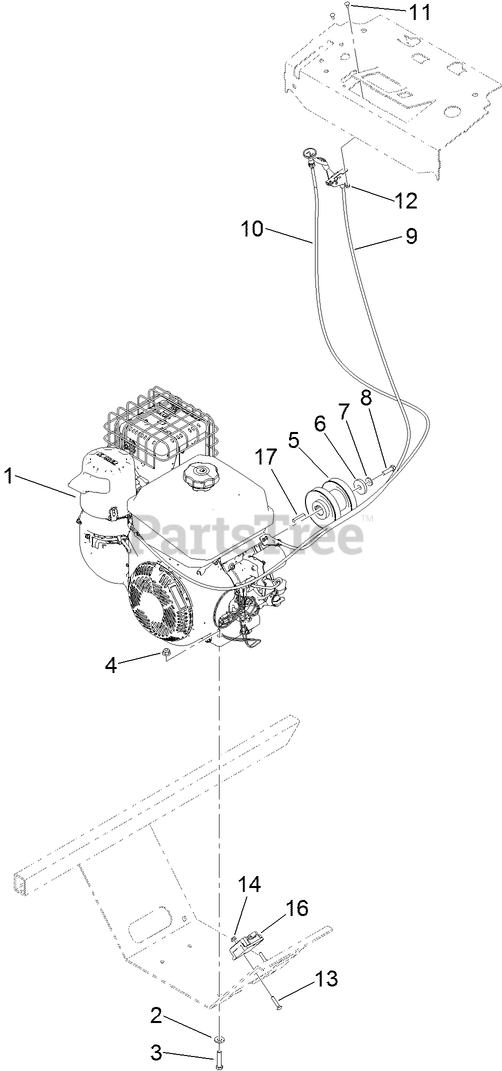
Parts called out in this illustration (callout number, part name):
2	WASHER-BELLEVILLE
3	SCREW-HH
4	NUT-HF, NI
5	PULLEY
6	WASHER-CLUTCH
7	WASHER-SPRING
8	SCREW-HH
9	CONTROL-THROTTLE
10	CABLE-CHOKE, PUSH/PULL
11	BOLT-CARR
12	NUT-LOCK, NI
13	SCREW-CARR
14	NUT-HF
16	REGULATOR
17	KEY-CRANKSHAFT
